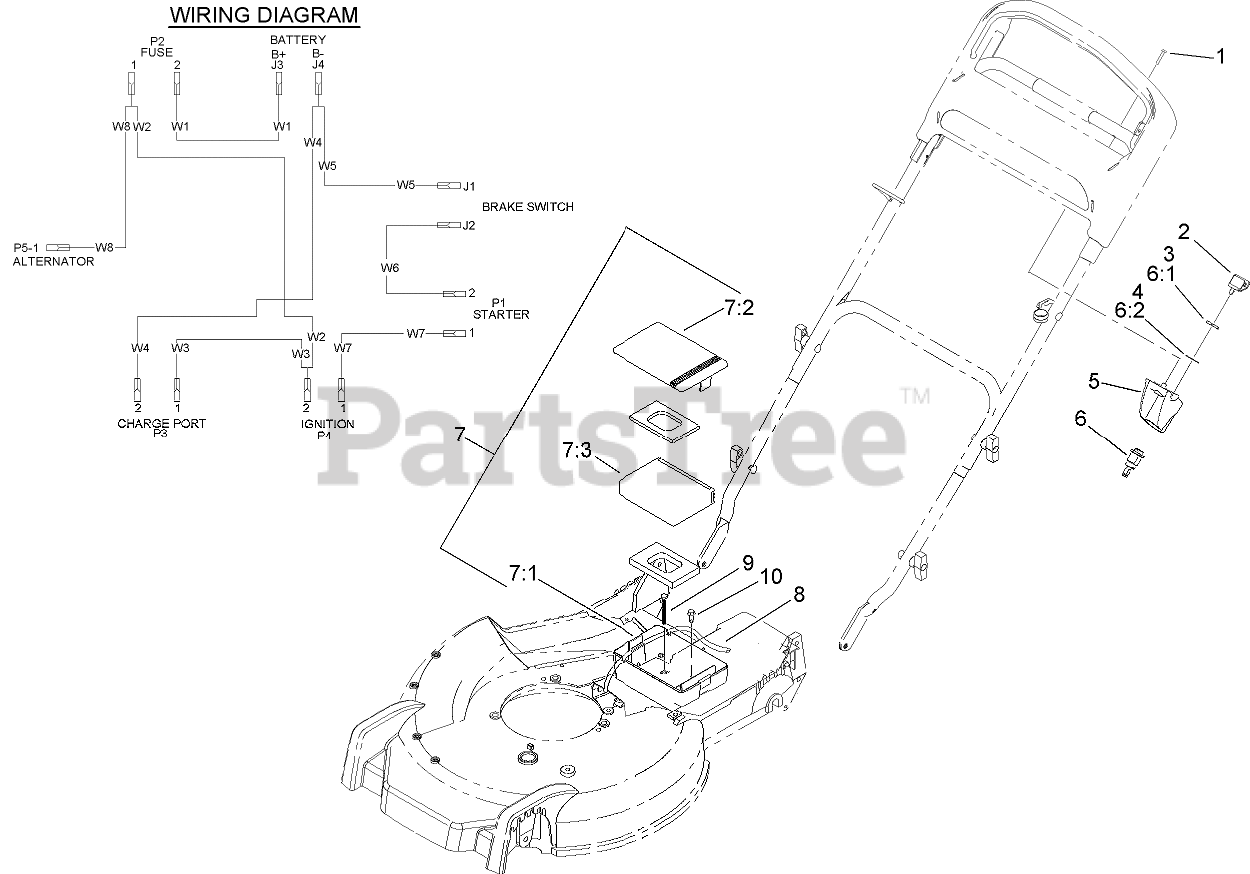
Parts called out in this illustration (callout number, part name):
1	SCREW-PPH, PLASTITE
2	KEY-IGNITION
3	NUT-HH
4	WASHER-TOOTH, INTERNAL
5	SWITCH-HOLDER
6	STARTER SWITCH ASM
6:1	WASHER-TOOTH, INTERNAL
6:2	NUT-HH
7	BATTERY ASM-PANASONIC
7:1	BOX-BATTERY
7:2	COVER-BATTERY
7:3	BATTERY-12V
8	HARNESS-WIRE
9	SCREW-SPECIAL
